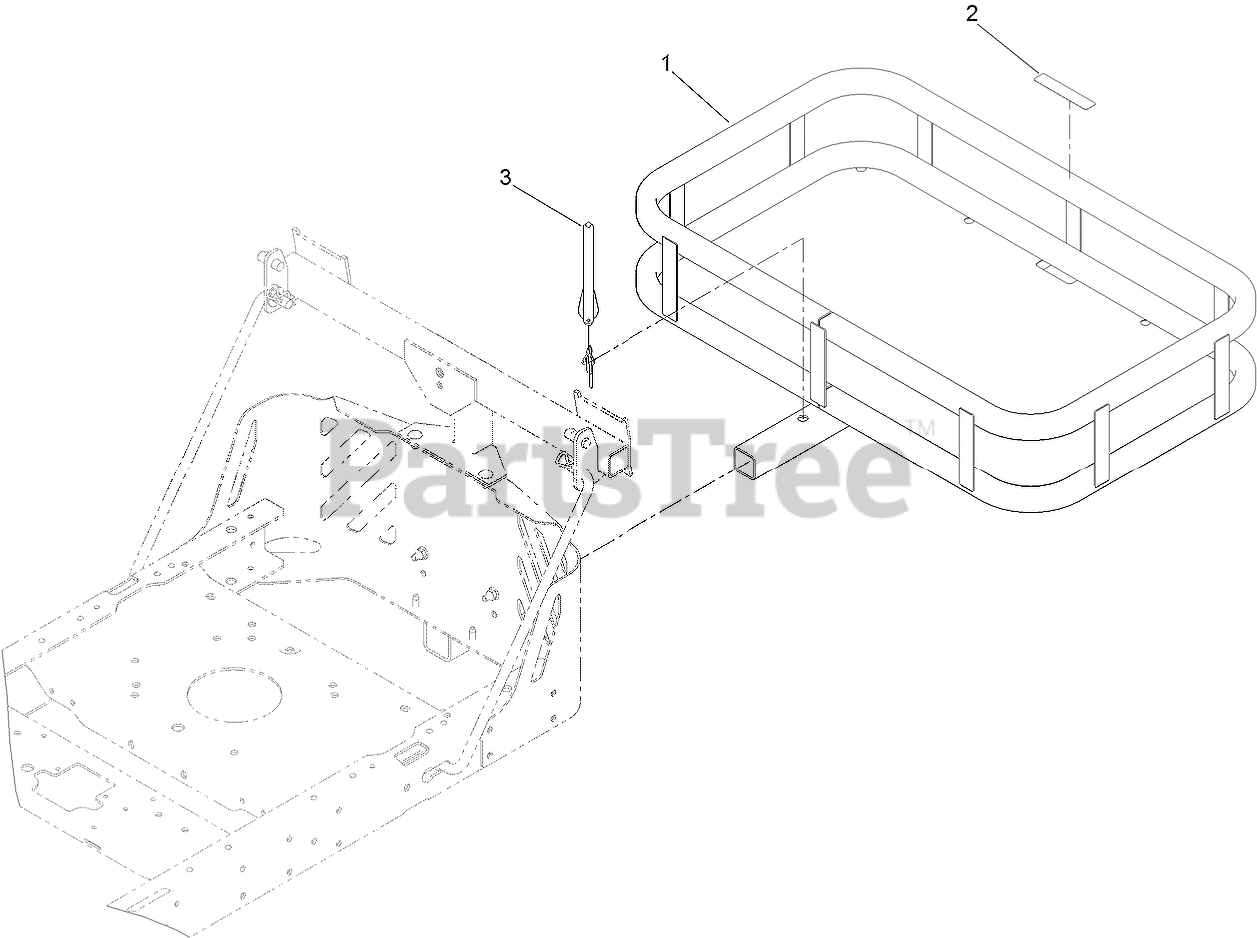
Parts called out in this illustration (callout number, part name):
1	TRAY-CARRIER
2	DECAL-MAXIMUM WEIGHT
3	PIN-ROPS
